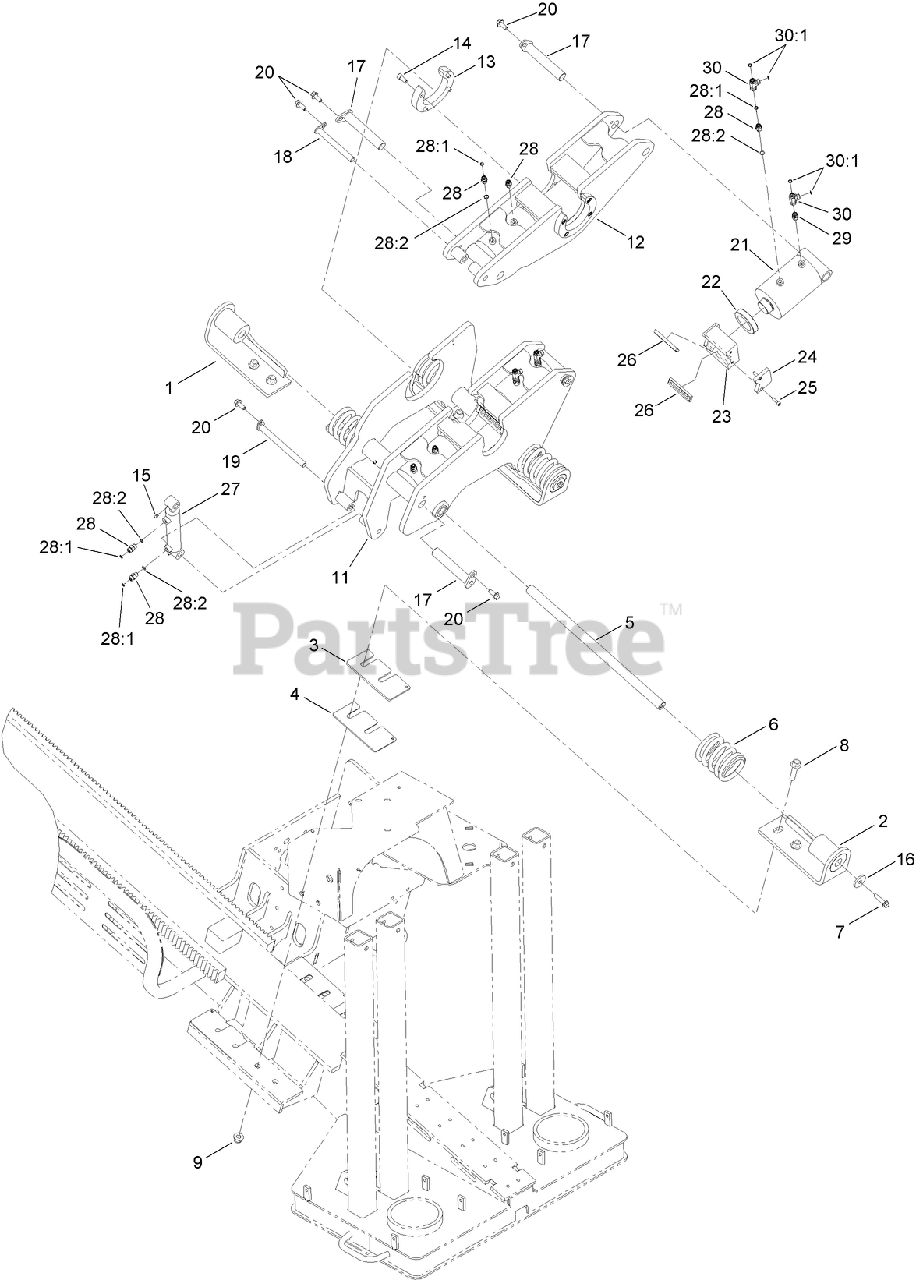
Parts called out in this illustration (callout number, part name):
1	BRACKET-MOUNTING, WRENCH
2	BRACKET-MOUNTING, WRENCH
3	SHIM-PLATE, WRENCH
4	SHIM-PLATE, WRENCH
5	PIN-WRENCH
6	SPRING-COMPRESSION
7	SCREW-HHF
8	SCREW-FLANGE
9	NUT-HHF
11	WRENCH-FRONT
12	REAR-WRENCH
13	GUIDE-WRENCH
14	SCREW-HSH
15	FITTING-GREASE
16	WASHER-FLAT
17	PIN-W/FLAG
18	PIN-RETAINNG
19	PIN-RETAINING
20	SCREW-HHF
21	HYD CYLINDER ASM
22	BUSHING-CYLINDER
23	HOLDER-DIE, WRENCH
24	RETAINER-DIE, WRENCH
25	SCREW-HSH
26	TONG-DIE
27	HYD CYLINDER ASM
28	FITTING-STRAIGHT
28:1	O-RING
28:2	O-RING
29	FITTING-ORIFICE
30	FITTING-TEE, SWIVEL NUT
30:1	O-RING
